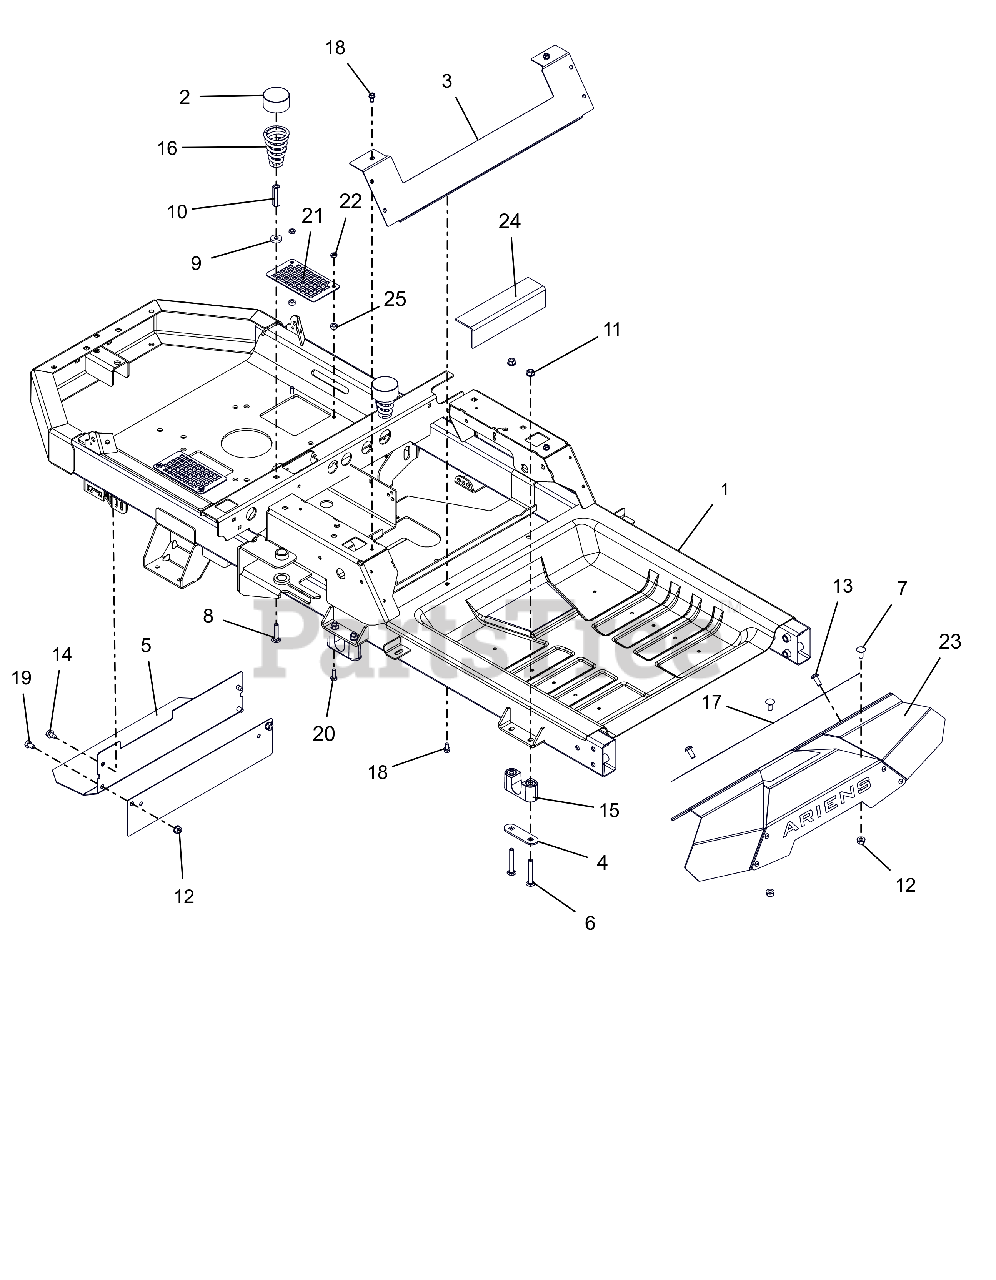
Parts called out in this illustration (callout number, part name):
1	KIT, IKON-X/XL FRAME (2016)
2	HUB CAP
3	PLATE, SEAT KICK
4	PLATE, BEARING SUPPORT
5	HEAT, SHIELD
6	BLT-RDHDSQSHNK .31-18X2.25 YWZ
7	BLT,RHSN .31-18X.75 G5 ZCC
8	BLT,RHSN .31-18X1.50 G5 ZCC
9	WSHR, FLT .328X.870X.179 ZCC
10	NUT, COUPLING 5/16-18 X 1 3/4
11	NUT,LK-CTR-FLG .31-18 GF ZCC
12	NUT-LK-TOP-FLG .312-18 GF ZCC
13	SCR-RDHDSKTAP .31-18 X .75
14	SCR,TAP .312-18X.50 HWH TR ZCC
15	BSHG, DECK LIFT PIVOT
16	SPRING, SEAT
17	GRIP TAPE, FOOT PLATE
18	SCR-TAP .25-20X.50 HWH ZCC
19	BLT, HEX .31-18X.50 GR5 ZCC
20	BLT, HEX .25-20X.75 G5 ZCC
21	GUARD, VENT
22	NUT-LK-CTR-JAM .250-20 GB ZCC
23	KIT, IKON FOOT REST W/DECAL
24	PAD, RUBBER-TANK
25	BSHG-SLV .265X.500X.219
